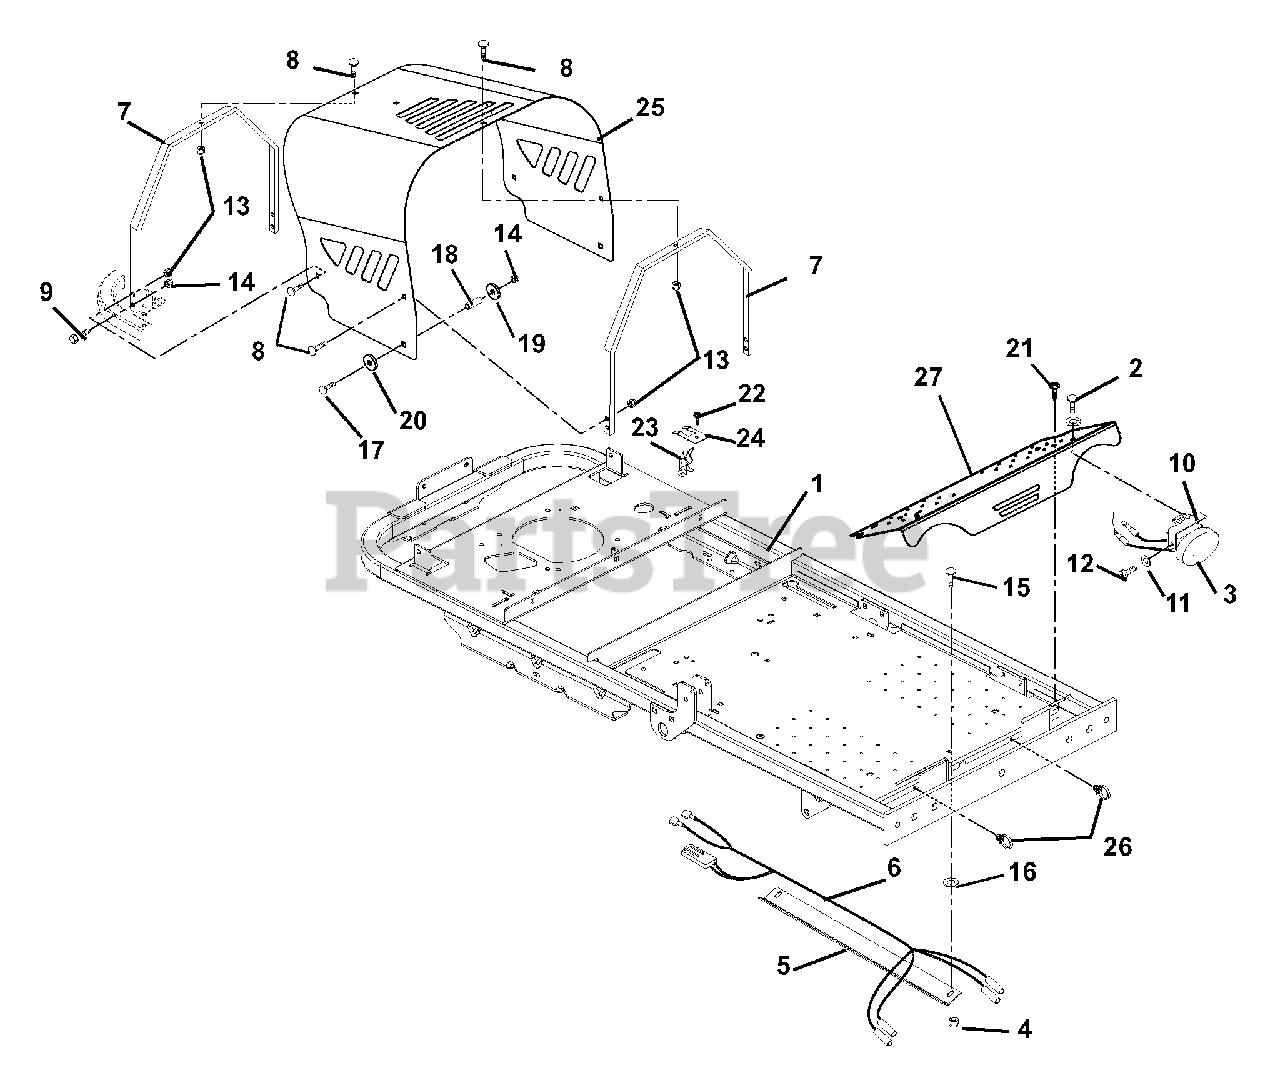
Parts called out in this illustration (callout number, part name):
1	WMT, FRAME
2	SCR-CAP BTHD.31-18X.50 GR5 YZ
3	LIGHT-CONS RIDE ON- SEE B-2124
4	@NUT-LK-NYL-FLG .31-18 YWZC
5	BKT-HARNESS
6	HARNESS, LIGHT
7	BRACE, HOOD
8	@BLT-RHDSSQNK .31-18X.62 G5YZ
9	BOLT-SHLDR .375-16X.150
10	WMT, LIGHT BRACKET
11	WSHR-LK 4MMX1MM REG CL ZINC
12	SCREW-M4X.07X8 SHCS CLZNC
13	@NUT-LK-TOP-FLG .31-18 YWZC
14	@NUT-LK-NYL-FLG .38-16 YWZC
15	@BLT-RDHDSQNK .31-18X1.00 G5YZ
16	WSHR-FL-STL .328X.87X.179 YWZC
17	@BLT-RDHDSQNK .38-16X2.50 G5YZ
18	BSHG, SPCR .390X.625X1.25 PM
19	WSHR-FL-STL .375X1.125X.065YWZ
20	@WSHR-FL-STL.531X1.06X.095YWZC
21	@SCR-TAP .31-18X.50 HWH TR YWZ
22	@SCR-TAP .25-20X.50 HWH TR YWZ
23	HOOD CLIP
24	BRACKET, HOOD CLIP
25	ENGINE HOOD
26	ROUTING CLIP (1/2" ID)
27	FOOTREST
